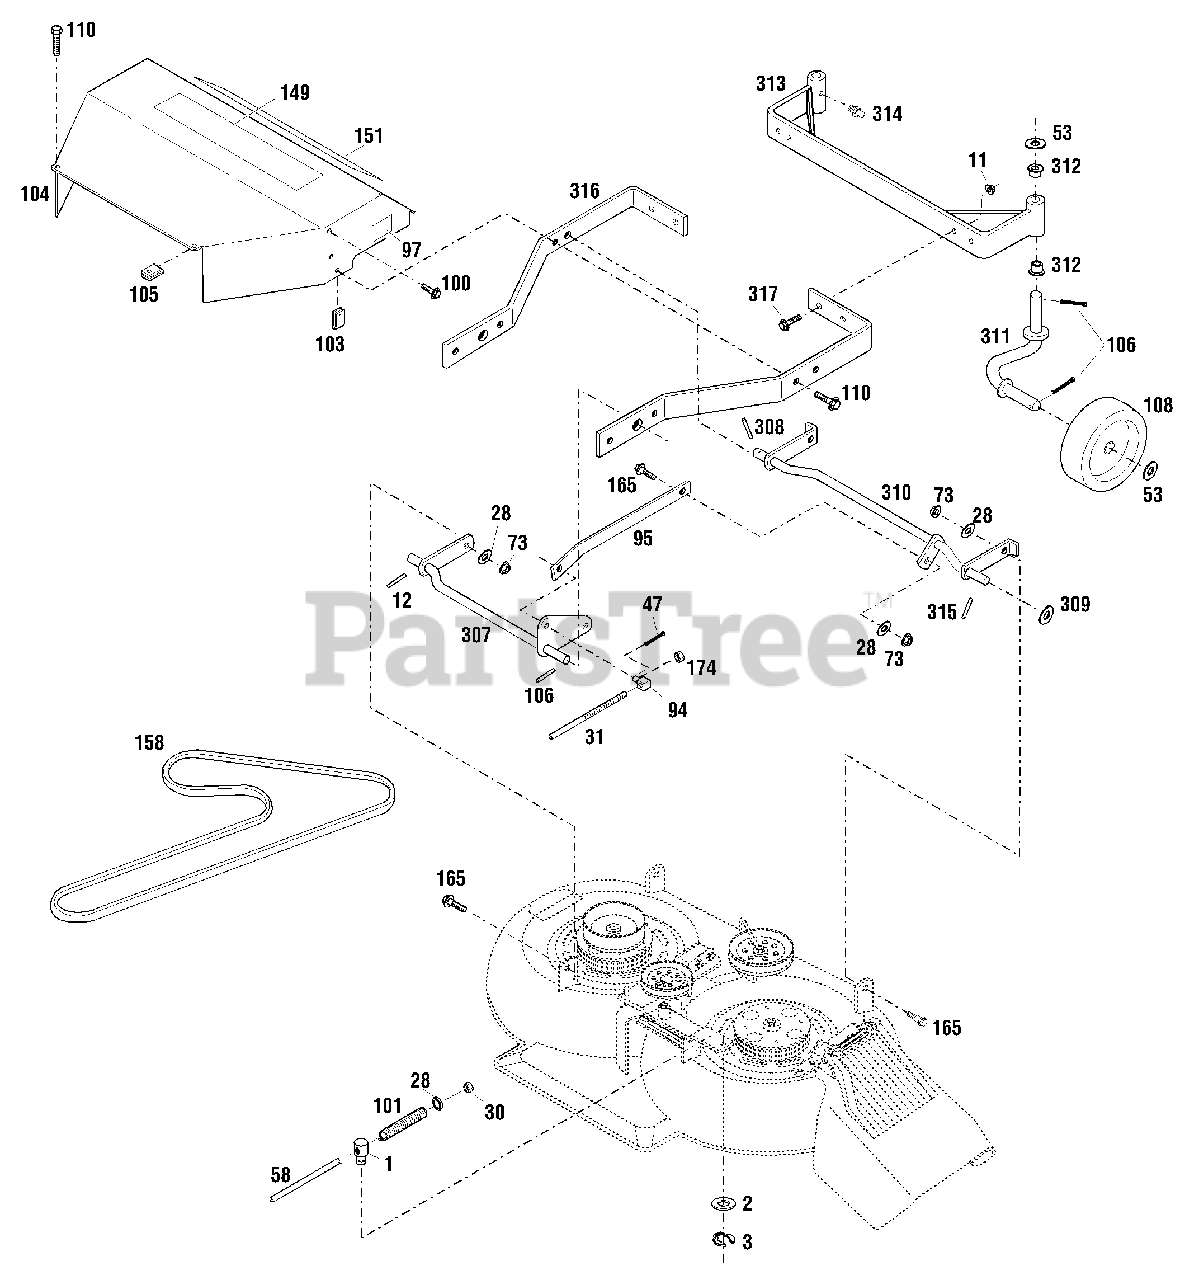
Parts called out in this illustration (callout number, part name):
3	Clip Ring
11	Flange Locknut, 3/8-16
28	Flat Washer, 3/8
30	Locknut, 3/8-16
31	Lift Crank
47	Cotter Pin
53	Special Washer
58	Lower Blade Rod
73	Flange Locknut, 3/8-16
94	Pivot Block
95	Leveler Bar
97	Cutting Height Decal
100	Tap Screw, #8 x 3/8
101	Compression Spring
103	Speed Nut, 5/16-18
106	Cotter Pin
108	Gage Wheel
110	Flange Lock Screw, 5/16 x 3/4
149	Logo Decal
151	33" Combination Deck Decal
165	Shoulder Bolt
174	Toplock Nut
307	Rear Lift Assembly
308	Roll Pin, 1/4 x 1
309	Flat Washer, 5/8
310	Front Lift Assembly
311	Spindle Assembly
312	Flange Bearing
315	Drive Pin, 1/4 x 3
